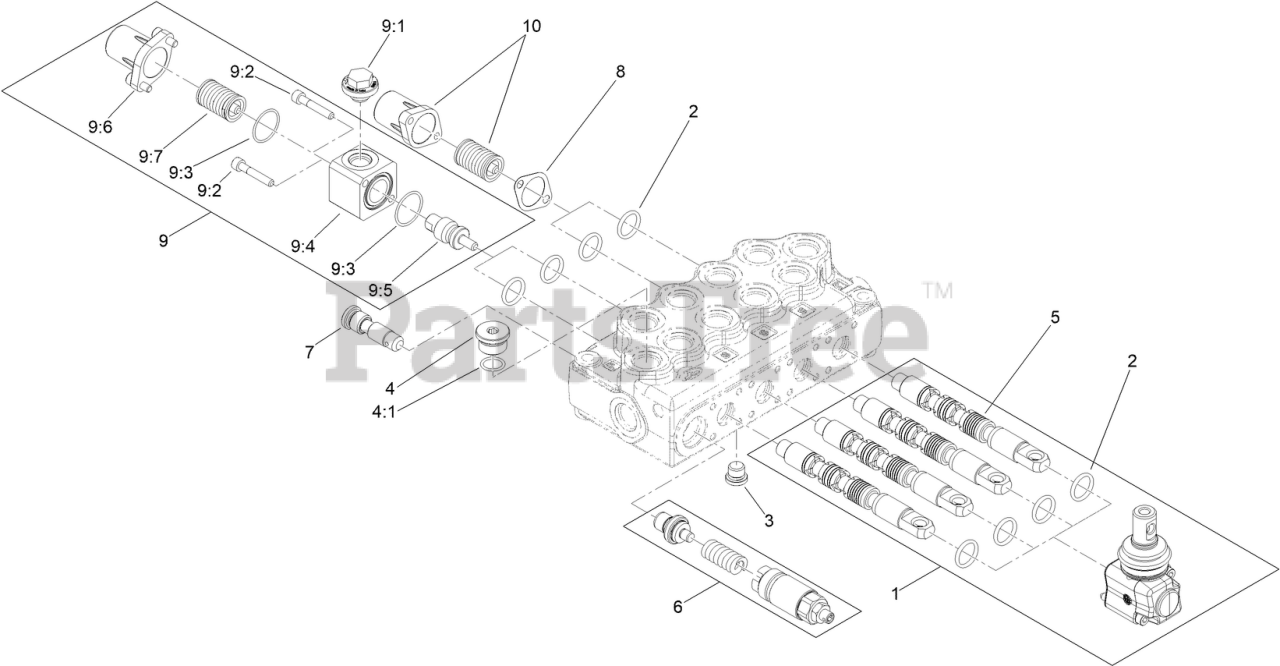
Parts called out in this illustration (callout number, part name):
1	LSG/S5 LEVER KIT WITH SCREWS
2	O-RING SEAL, 70 SH
3	SAE 4 PLUG
4	PLUG-HEX
4:1	O-RING
5	SPOOL-VALVE
6	VMD5 (JN) INLET PART
7	KIT-VALVE BODY
8	GASKET
9	S5 COMMAND KIT
9:1	Plug
9:2	Screw
9:3	ORING
9:4	Block
9:5	Pin
9:6	End Cap
9:7	Spring
10	S5 END CAP KIT
